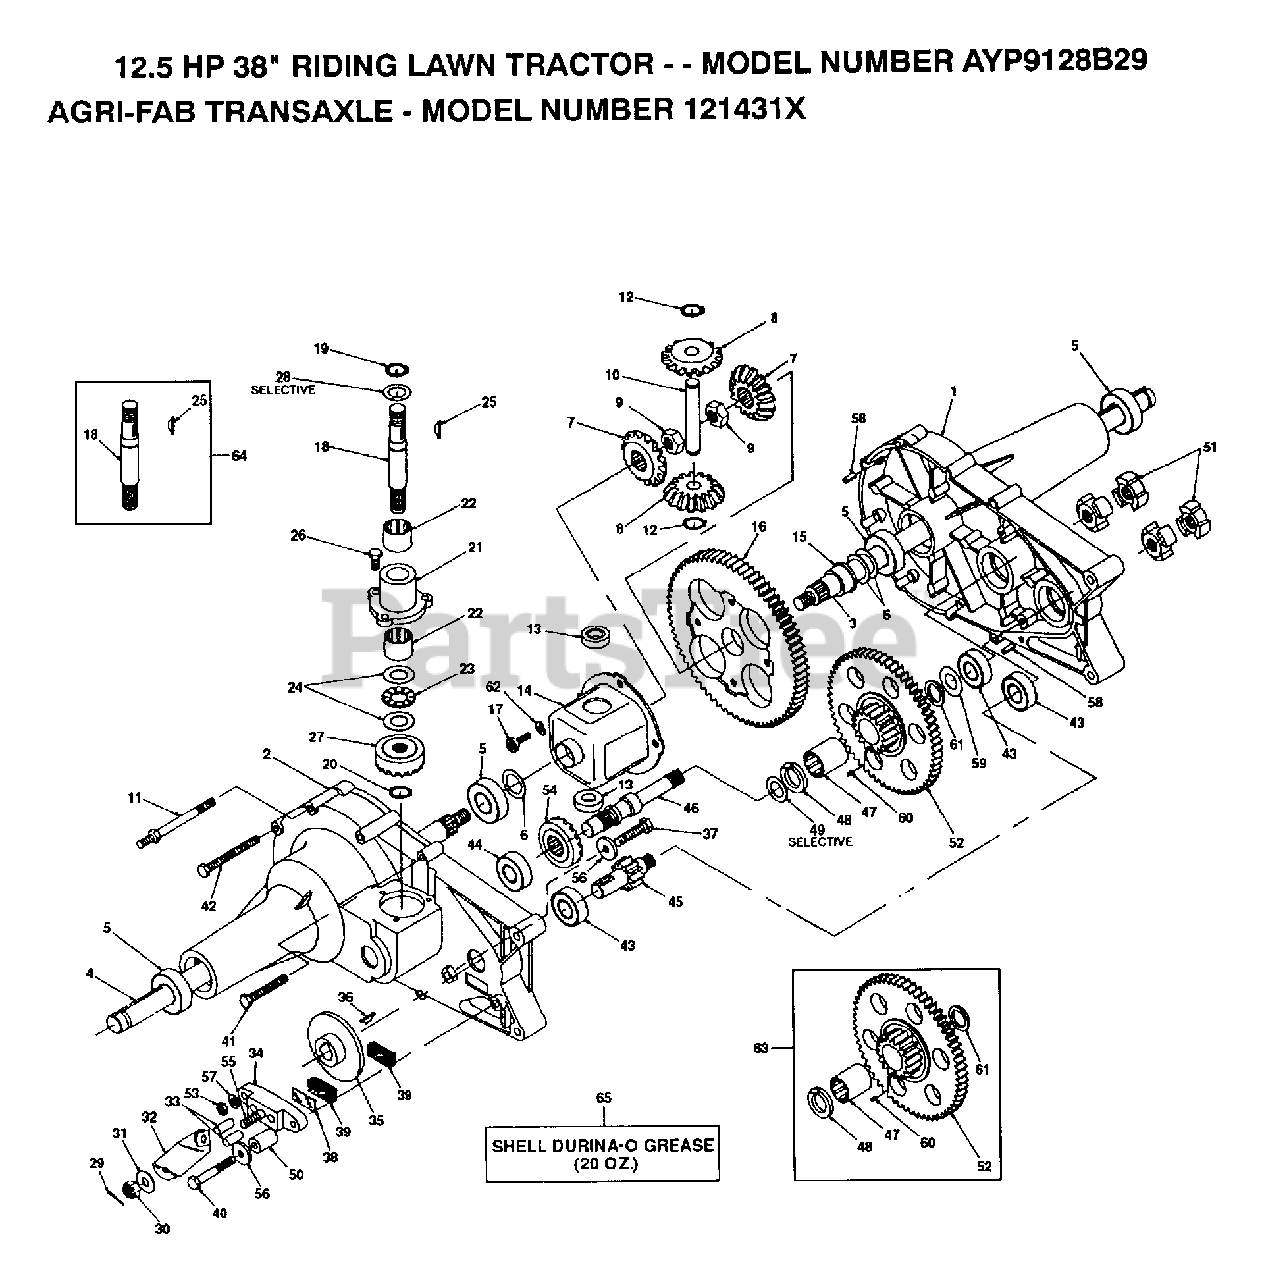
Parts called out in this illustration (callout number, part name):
1	HSG HALF LH-44077
2	HSG HALF RH-44076
3	AXLE LH -44273
4	AXLE RH-44272
5	BEARING.44121.AGR
6	WASHER -44008
7	GEAR MITER -44096
8	GEAR MITER -44097
9	NUT -44133
10	SHAFT CROSS
11	SCREW-STUD -44271
12	SNAP RING -44146
13	"THRUST, BEARING -44128"
14	HOUSING.ASM.DIFF.-62590
15	"FLANGE, BEARING-44129"
16	GEAR
17	BOLT -44126
18	SHAFT INPUT-44270
19	SNAP RING -44145
20	RET RING (44144)
22	"NEEDLE, BEARING 44099"
23	BEARING.NEE.44139
24	WASHER-44109
25	KEY.44136.HYDRO
26	SCREW
28	WASHER -44371
29	PIN COTTER -44101
30	WASHER -44150
31	WASHER FLAT -44130
32	ARM BRAKE 23710
33	PIN BRAKE ACTUATO -44127
34	BRAKE YOKE
35	DISC BRAKE -(44090)
36	KEY -44143
37	SCREW -44277
38	PLATE PUCK -44134
40	SCREW -44300
41	SCREW -44123
42	SCREW -44124
44	"BALL, BEARING -44232"
45	SHAFT PINION 44083
46	SHAFT DRIVE-44080
47	NEEDLE BEARING -44342
48	THRUST.BRONZE -44343
49	THRUST.BRONZE -44343
50	SPACER -23711
51	COUPLING- 44084
52	GEAR.60/17.44523
53	NUT -43178
54	PINION-DR.44079
55	BOLT SQ HD
56	WASHER -44278
57	WASHER -44137
58	PIN ROLL-44269
59	WASHER -44125
60	DOWEL PIN -44346
61	SEAL GREASE -44394
62	WASHER.43177.AGRI
63	ASS'Y GEAR REDUCT
65	GREASE.50416.10OZ
